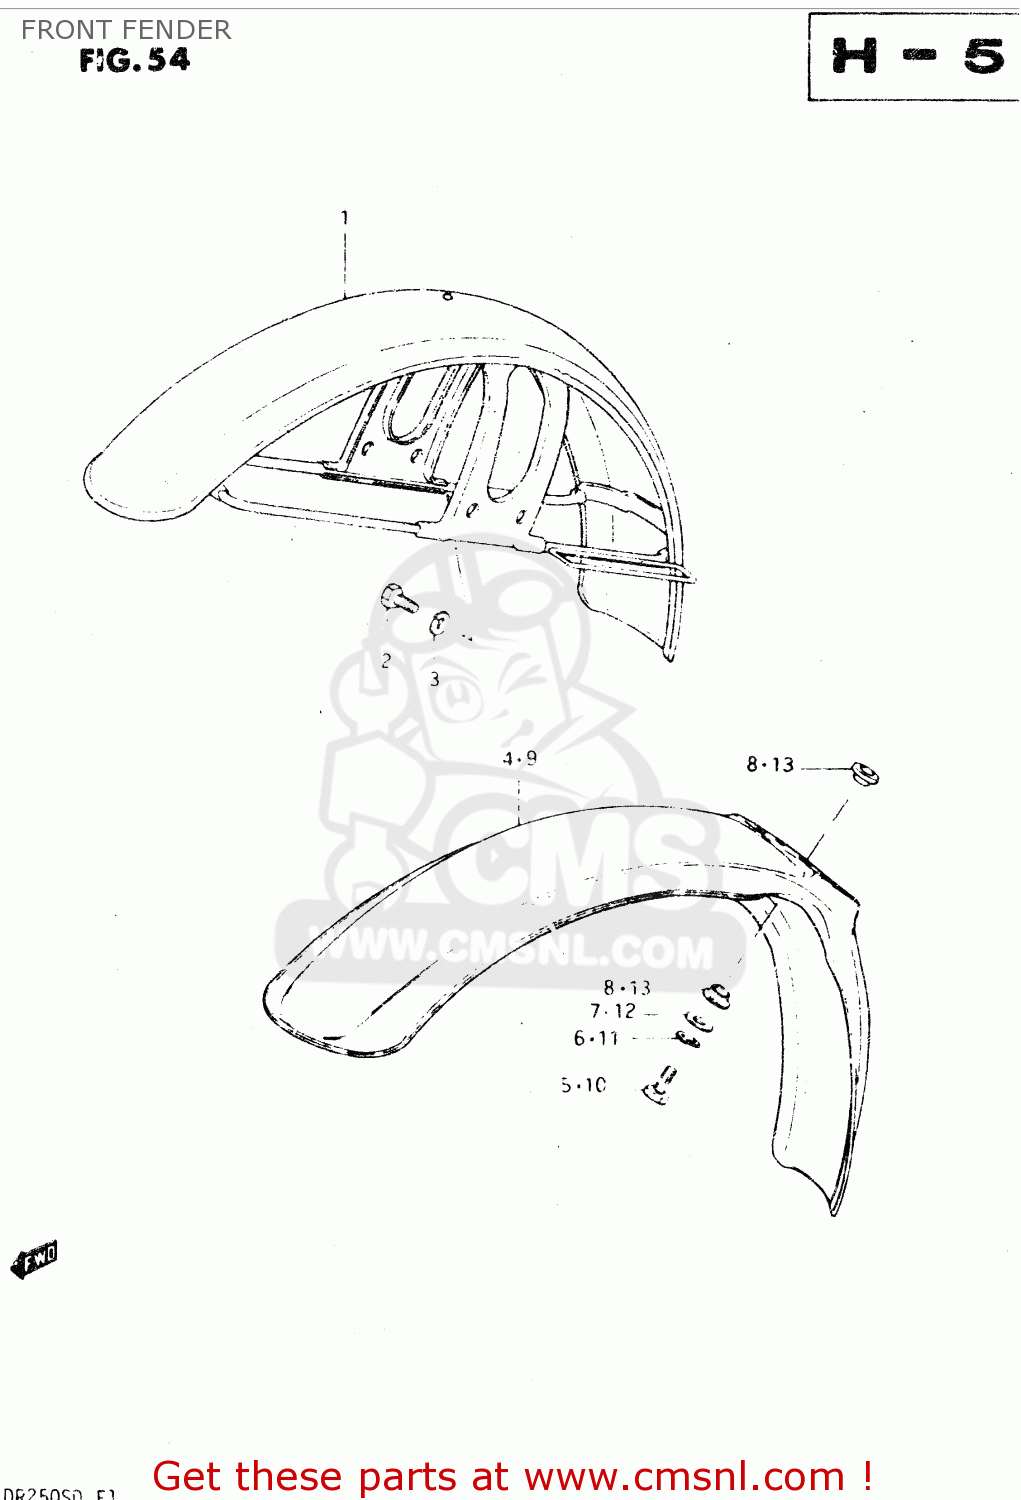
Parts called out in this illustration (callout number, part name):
1	FENDER,FR
2	BOLT
3	LOCK WASHER
4	FENDER, FRONT (BLUE)
5	BOLT, UPPER
6	LOCK WASHER
7	WASHER
8	SPACER
9	FENDER, FRONT (BLUE)
10	BOLT, UPPER
11	LOCK WASHER
12	WASHER
13	SPACER
